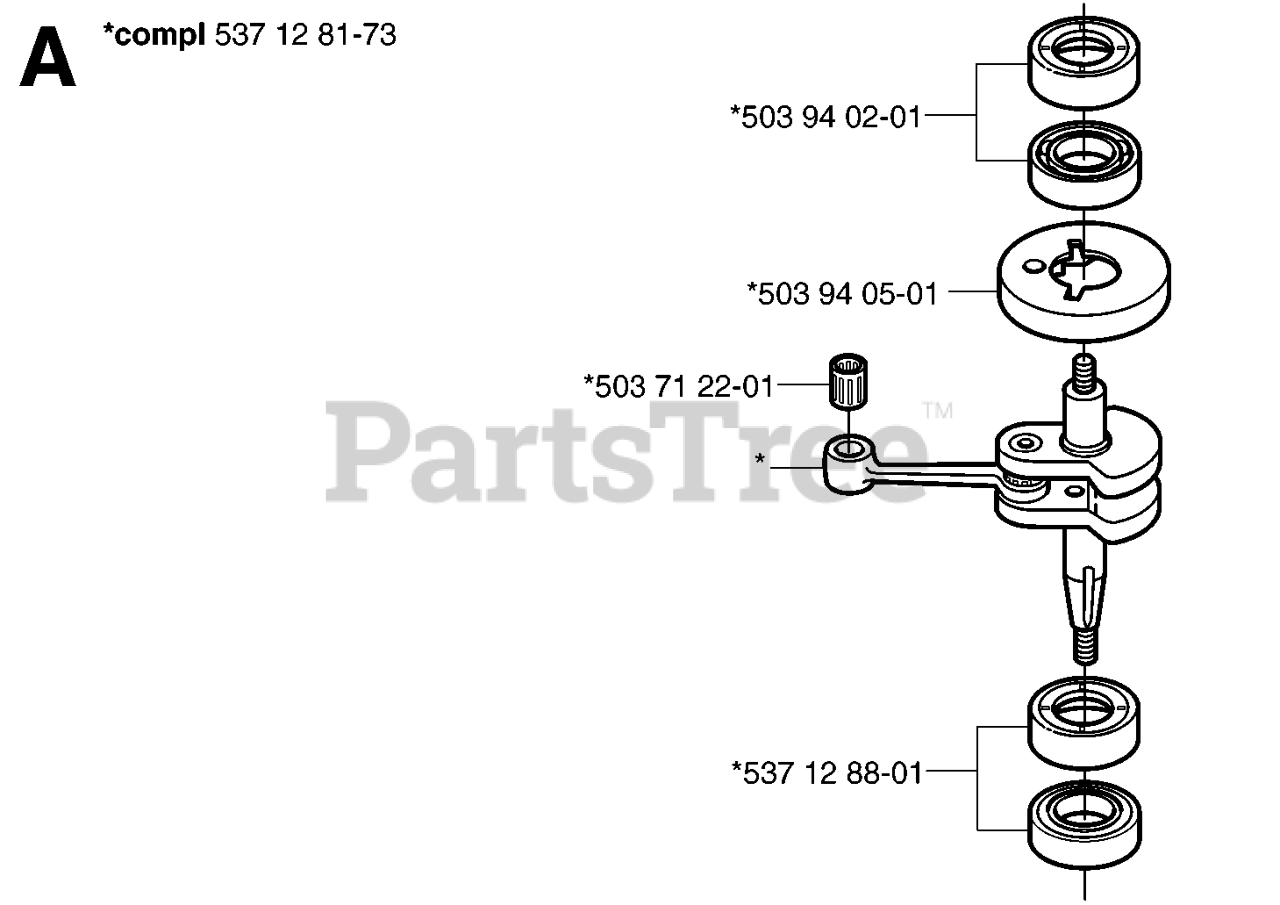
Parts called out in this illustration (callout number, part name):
1	Housing, Lower
2	Assembly, Upper Housing
3	Seal, Lip
8	Bearing, Thrust 30 x 52 x 13
13	Block, Cylinder Assembly
15	Seal, Lip
18	Shaft, Motor
19	Bearing, Thrust 42 x 68 x 16
23	Block, Cylinder Assembly
24	Seal, Lip 10 x 25 x 7
25	Actuator, Bypass
26	Center Section Assembly Kit
27	Seal, Lip 26 x 42 x 8
28	Ring, Retaining
29	Washer 26 x 35 x 1
34	Oil Filter Element
35	Arm, Bypass
36	Ring, Retaining
37	Arm, Actuating
38	Pin, Actuating
39	Bolt 5/16-24 x 1-3/4
40	Nut, Nylon Insert Hex Lock 5/16-24
41	Brake Rotor/Stator Kit
43	Washer 7/8 O.D. x 7/16 x .060
44	Differential Assembly
52	Washer 3/4 x 1.5 x .13
53	Seal .75 x 1.25 x .250
56	Shaft, Input
58	Bolt 1/4-20 x 1.38
59	Pin .5 OD x .43 ID x .750
62	Arm, Control
63	Puck, Dampener
64	Set Screw
68	Spring
69	Stud 5/16-24
92	Spring, helical compression
93	Washer, Block Thrust
98	Sleeve Bearing
99	Seal, Wiper
113	Cap, Vent Assembly
114	Fitting, O-Ring Assembly
119	Spacer
134	Nut, Castle 5/16-24
135	Pin, Cotter
139	Spring, Compression
140	Nut, Hex 5/16-24
